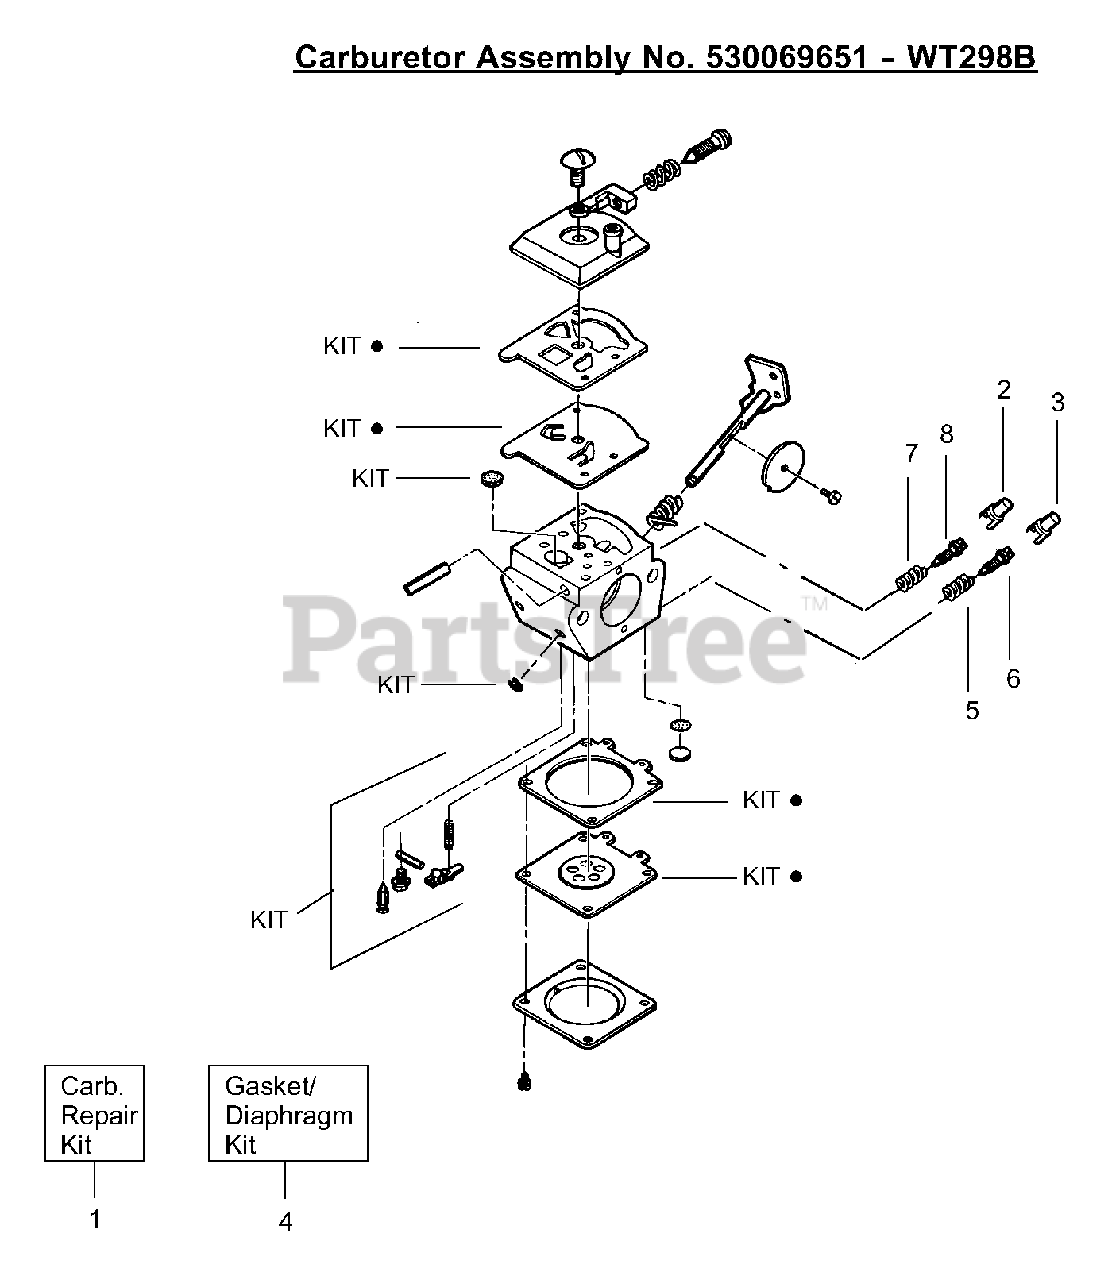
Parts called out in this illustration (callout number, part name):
1	Carburetor Repair Kit
2	Limiter Cap (High-Red)
3	Limiter Cap (Low-Blue)
4	Gasket/Diaphragm Kit
5	Needle Spring-Low Speed
6	Needle-Low Speed
7	Needle Spring-High Speed
8	Needle-High Speed
530069651	Carburetor Assembly - WT298B
